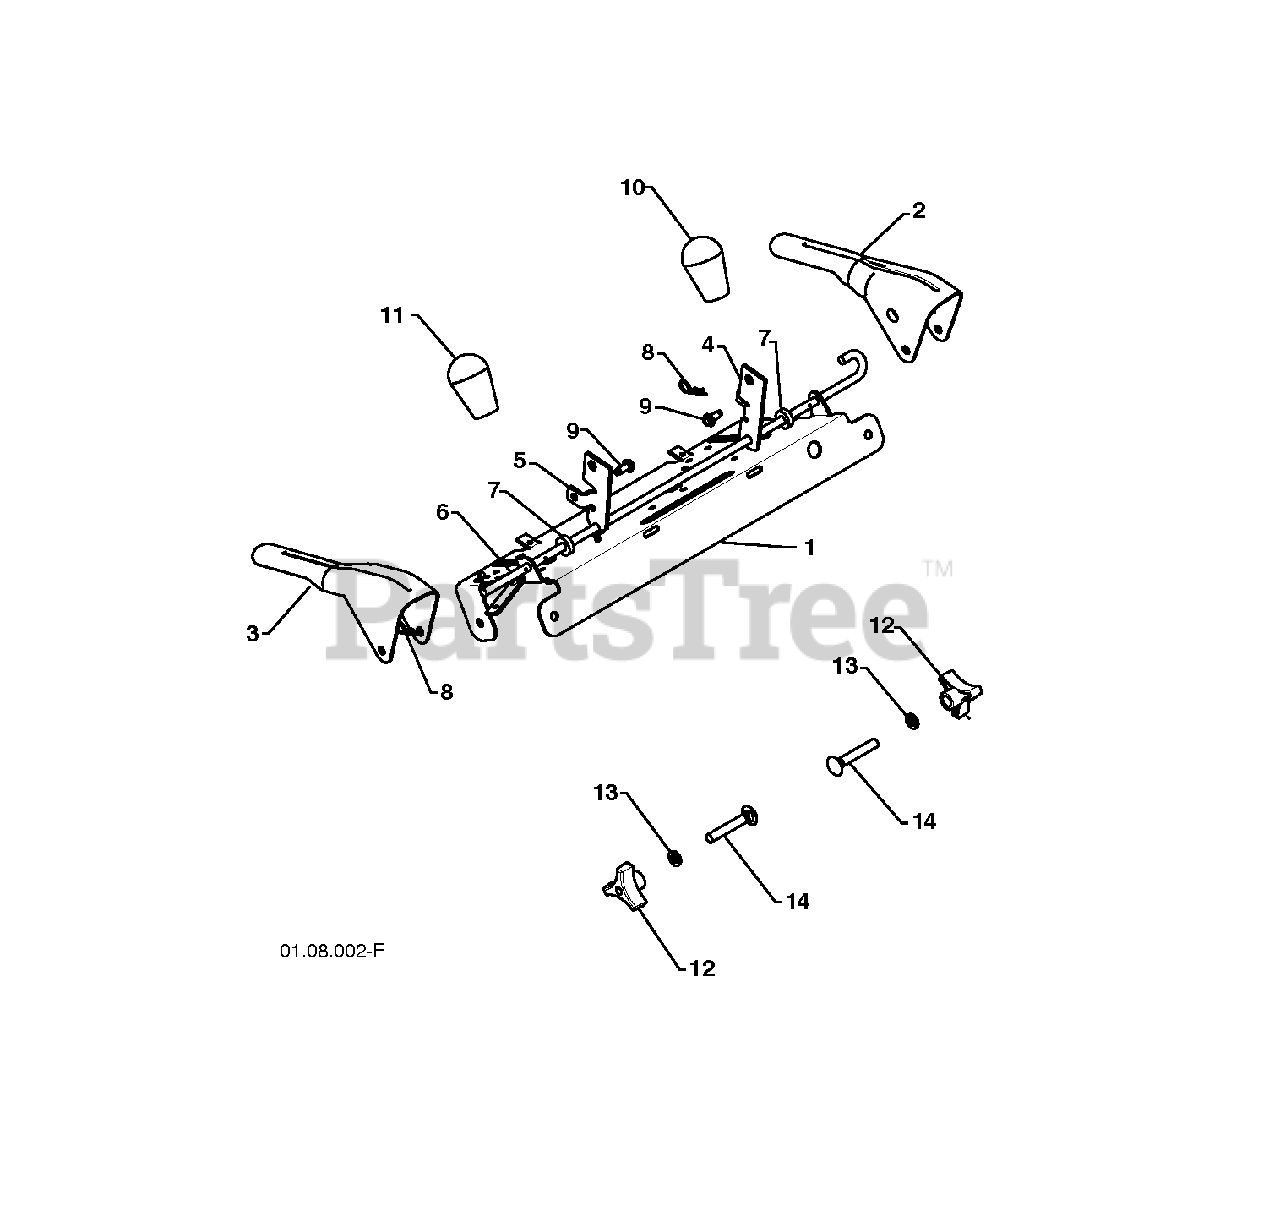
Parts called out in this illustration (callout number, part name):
1	PANEL.CONTROL
2	LEVER.CONTROL.LH.431
3	LEVER.CONTROL.RH.431
4	ARM.TRACTION.ROD.YZ
5	ARM.IMPELLER.ROD.431
6	BAIL.CONTROL.INTERLOCK
7	SPACER.CONTROL.LEVER
8	SPRING RETAINER
9	SCREW 14-20 X 5/8
10	KNOB LEVER, BLACK
11	RED KNOB SHIFTER
12	KNOB.HANDLE.3/8.TRI-POINT.BLAC
14	BOLT 3/8-16 X 2-1/4
